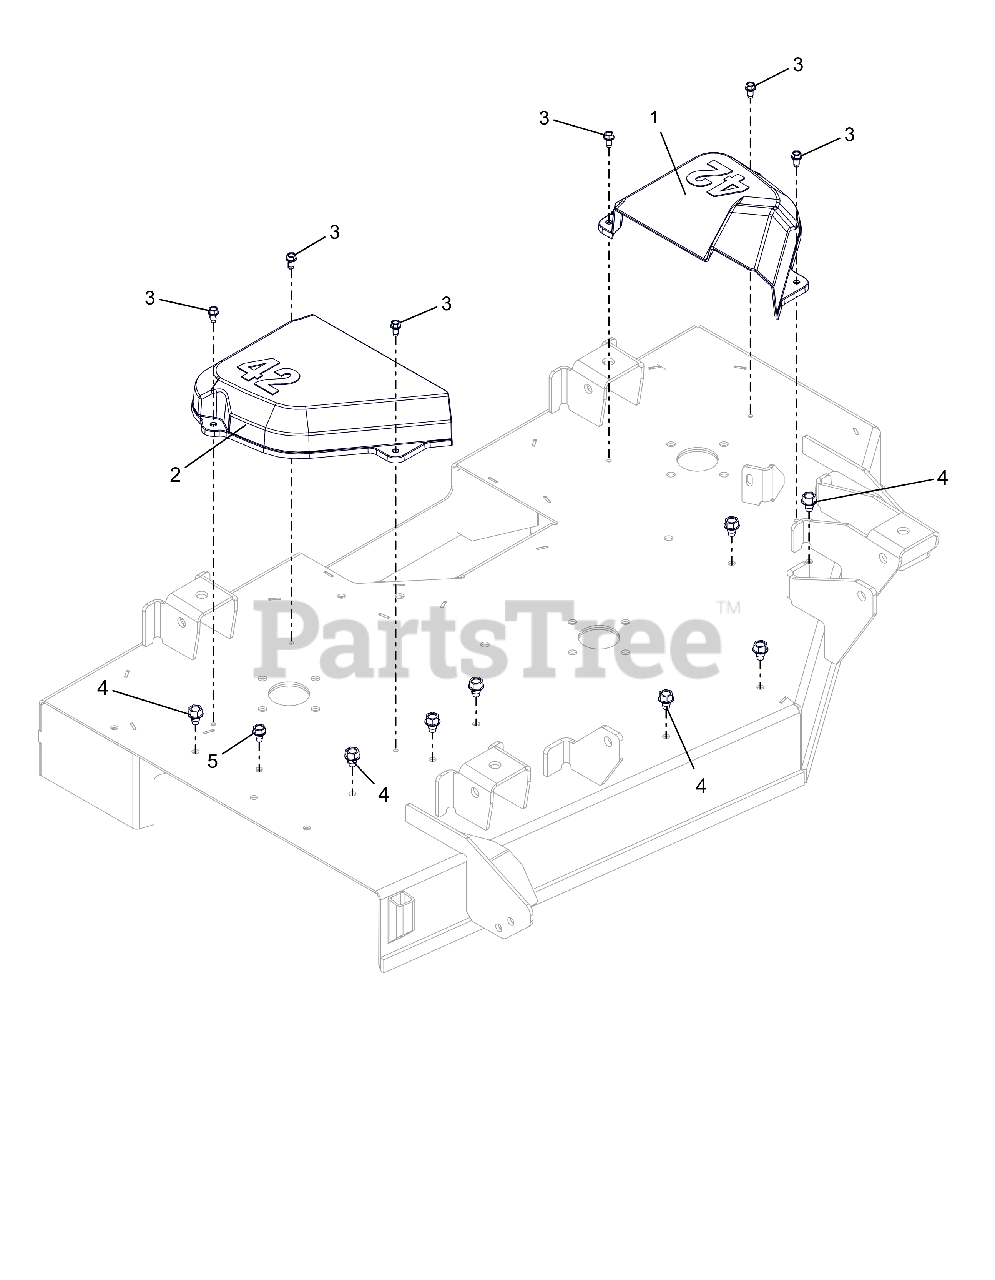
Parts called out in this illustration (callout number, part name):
1	COVER, BELT 42" LH
2	COVER, BELT 42" RH
3	SCR-TAP .25-20X.50 HWH ZCC
4	SCR,TAP .375-16X.50 HWH TR ZCC
5	@SCR-TAP .31-18X.50 HWH TR YWZ
